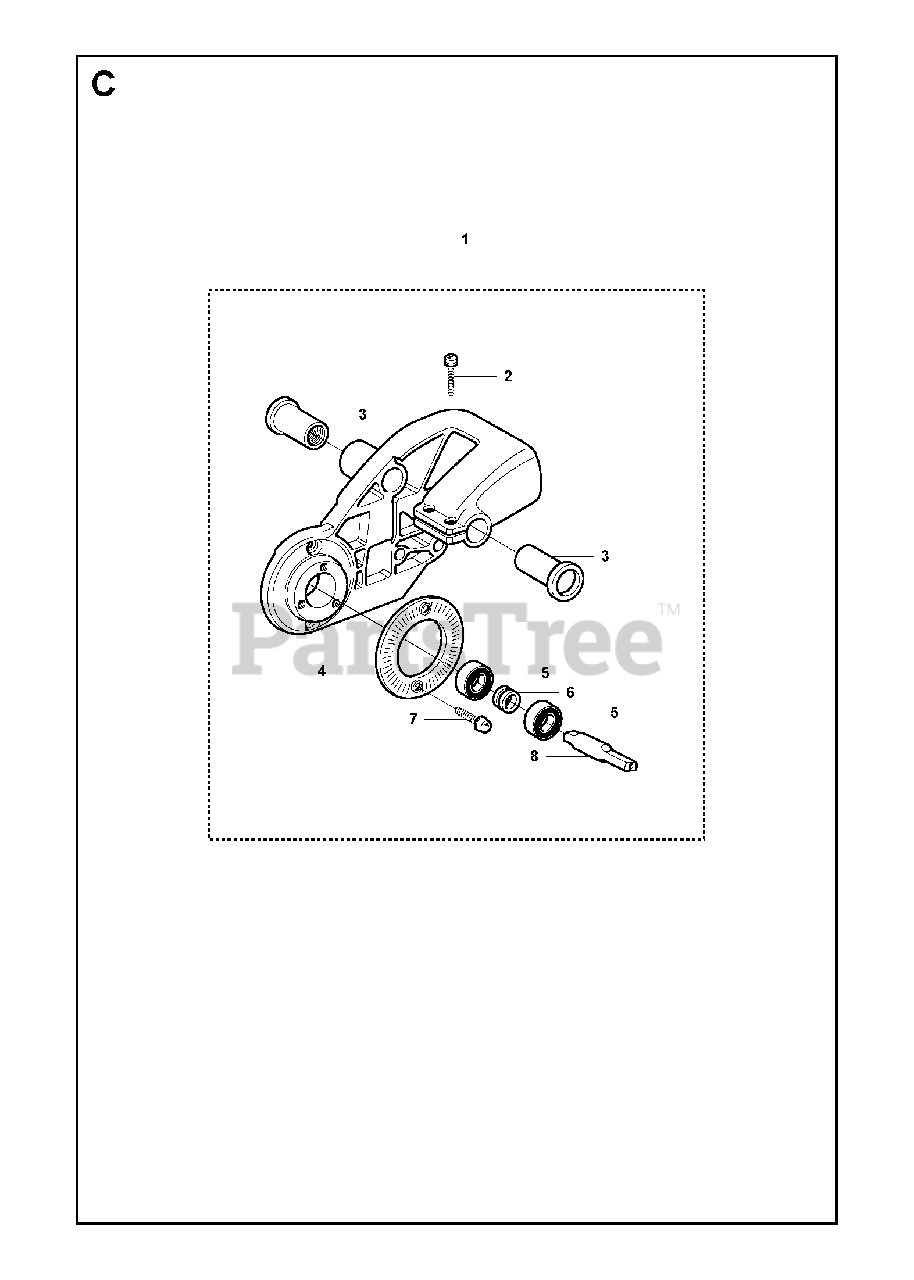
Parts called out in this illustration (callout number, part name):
1	BEARING HOUSING14" Incl. 2 - 8
1	BEARING HOUSING16" Incl. 2 - 8
2	SCREW IHSCFM
5	BALL BEARING
7	SCREW IHSCFM
